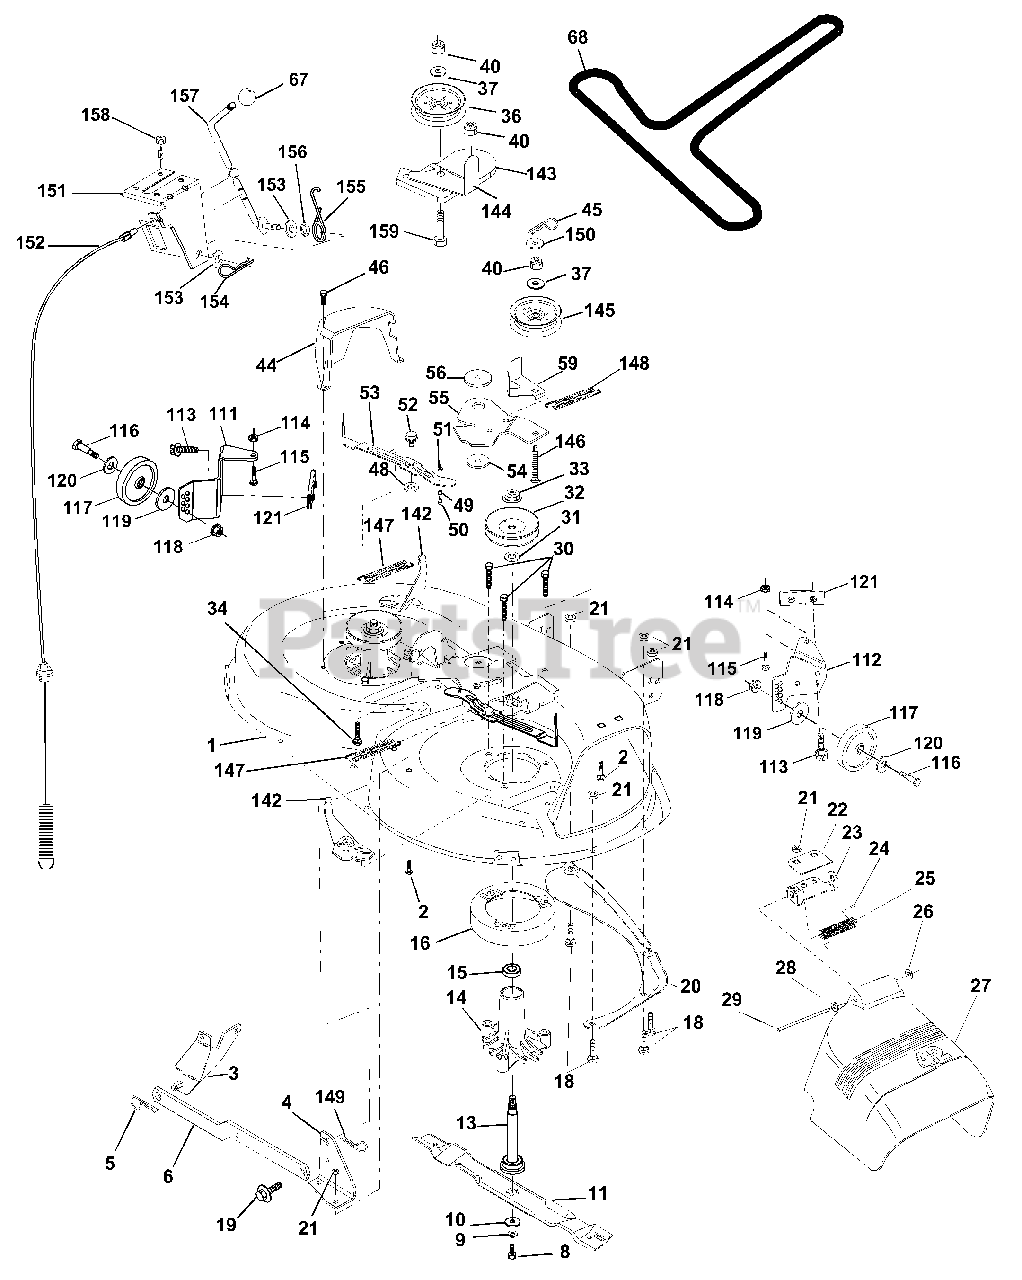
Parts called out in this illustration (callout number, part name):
1	Mower Deck Assembly, 42"
2	Bolt
3	Bracket Asm Fr. Sway Bar 3/42
4	Bracket Asm Deck 42" Sway Bar
5	Retainer Spring
6	Arm, Suspension, Rear
8	Bolt 3/8-24 x 25 Grade 8 patched
9	Washer, Lock
10	Washer, Hardened
11	Blade
13	Shaft Assembly, Mandrel, Vented
14	Housing, Mandrel, Vented
15	Bearing, Ball, Mandrel
16	Stripper, Vented Mower Deck
18	Bolt, Carriage 5/16-18 x 5/8
19	Bolt, Shoulder
20	Baffle, Vortex
21	Nut
22	Stiffener Bracket
23	Bracket, Deflector Mower 42"
24	Cap, Sleeve 80 x 112 Blk Mower
25	Spring, Torsion, Deflector 2 52
26	Nut, Push Phos & Oil
27	Shield, Deflector 42" Blk
28	Washer 11/32 x 5/8 x 16 Gauge
29	Rod, Hinge 42" 6 75 W/G
30	Screw Thdrol Washer Head
31	Washer, Spacer Mower Vented
32	Pulley, Mandrel
33	Nut, Toplock 9/16
34	Bolt
35	Fastener, Christmas Tree
36	Pulley, Idler, Flat
37	Washer 13/32 x 13/16 x 16 Gauge
40	Nut
44	Guard, Mandrel, LH
45	Retainer
46	Screw, Thdrol 1/4-20 x 5/8 T
48	Washer, Hardened
49	Roller Assembly, Cam Follower
50	Bolt, Shoulder #10-24 Grade 5
51	Locknut
52	Bolt, Shoulder 5/16-18 UNC
53	Arm Assembly, Pad, Brake
54	Washer, Hardened
55	Arm, Idler
56	Spacer, Retainer
59	Guard TUV Idler
67	Knob
68	V-Belt, 42" Mower
111	Bracket, Gauge, Wheel LH
112	Bracket, Gauge, Wheel RH
113	Screw Tapping 5/16-18 Unc
114	Nut, Keps 5/16 - 18 UNC
115	Bolt, Carriage 5/16-18 x 1/2
116	Bolt, Shoulder
117	Wheel, Gauge
118	Nut Centerlock 3/8-16
119	Washer 3/8 x 7/8 x 14 Ga.
120	Washer 17/32 x 15/16 x 12 Ga.
121	Bracket, Extruded
142	Arm Spring Brake Mower
143	Bracket Arm Idler 42"
144	Keeper Belt 42" Clutch Cable
145	Pulley Idler Flat
146	Bolt Carriage Idler
147	Spring Extension
148	Spring Return Idler
149	Retainer Spring Yellow
150	Washer 9/32 x 3/4 x 16 Ga.
151	Bracket Clutch Cable
152	Clutch Cable 42"
153	Washer Flat 3/8" Type B
154	Spring Retainer
155	Spring Retention LVR CLTCH CAB
156	Spacer Clutch Cable
157	Rod Clutch Cable 3/8"
158	Screw Hex Thd Cut 1/4-20 x 5/8
159	Bolt Rdhd Sqn 3/8-16 UNC x 1-3/4
